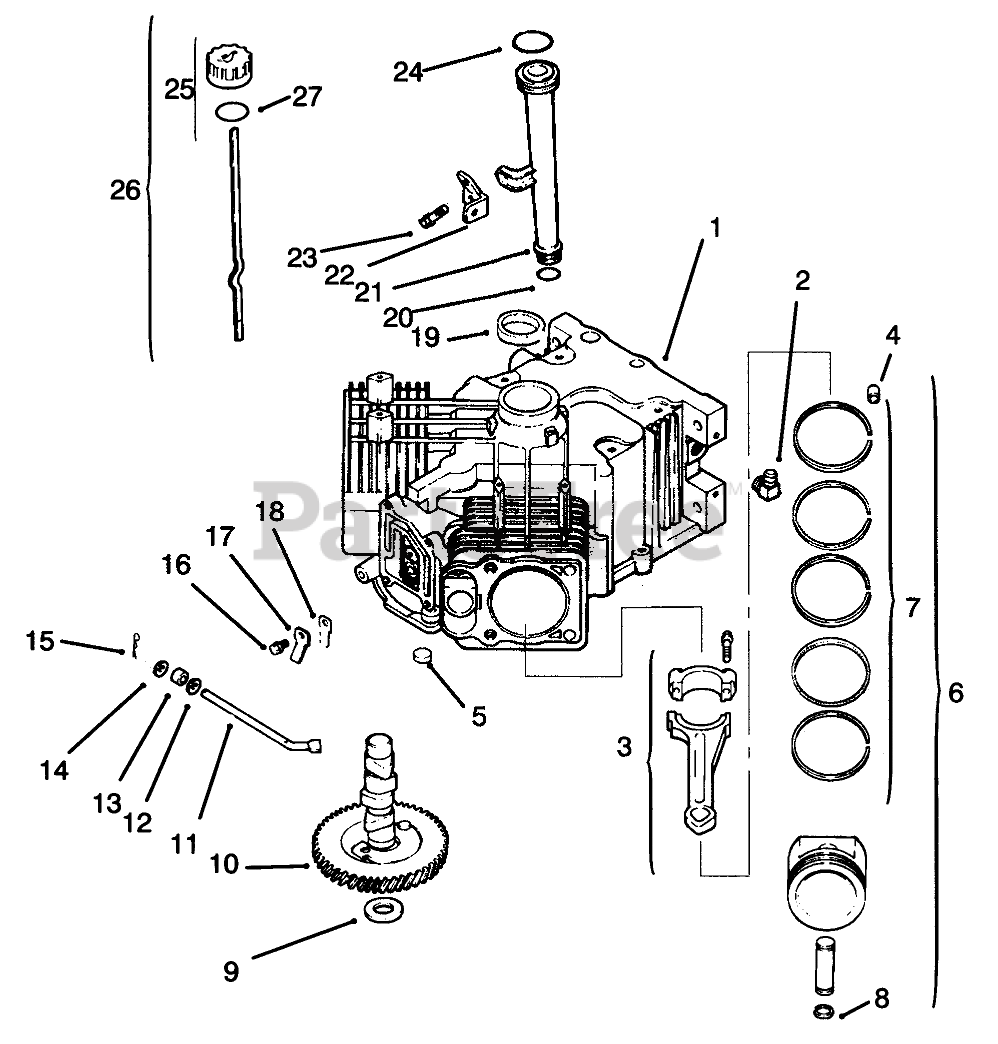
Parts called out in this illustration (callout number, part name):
1	Short Block (Only On: 72103)
2	Connector-90 DEG (Only On: 72103)
3	Connecting Rod STD (Only On: 72103)
3	Connecting Rod .25 (Only On: 72103)
4	Dowel-Locating (Only On: 72103)
5	Plug-Cup (Only On: 72103)
6	Piston ASM STD INCL 4/7/8 (Only On: 72103)
6	Piston ASM .25 INCL 4/7/8 (Only On: 72103)
6	Piston ASM .50 INCL 4/7/8 (Only On: 72103)
7	Ring Set STD INCL 4/8 (Only On: 72103)
7	Ring Set .25 INCL 4/8 (Only On: 72103)
7	Ring Set .50 INCL 4/8 (Only On: 72103)
8	Retainer-Piston Pin (Only On: 72103)
9	Shim-Camshaft A/R (Only On: 72103)
10	Camshaft (Only On: 72103)
11	Shaft-Governor Cross (Only On: 72103)
12	Washer-Flat (Only On: 72103)
13	Seal-Governor Shaft (Only On: 72103)
14	Washer-Flat (Only On: 72103)
15	Pin-Governor Hitch (Only On: 72103)
16	Screw M5x0.8x10 (Only On: 72103)
17	Retainer-Reed (Only On: 72103)
18	Beed-Breather (Only On: 72103)
19	Seal-Oil (Only On: 72103)
20	O Ring-Lower Fill Tube (Only On: 72103)
21	Tube-Oil Fill (Only On: 72103)
22	Bracket-Oil Fill Tube (Only On: 72103)
23	Screw M5x0.8x16 (Only On: 72103)
24	O Ring-Upper Fill Tube (Only On: 72103)
25	Dipstick INCL 26-27 (Only On: 72103)
26	Kit-Oil Cap INCL 3 (Only On: 72103)
27	O Ring-Fill Cap (Only On: 72103)
